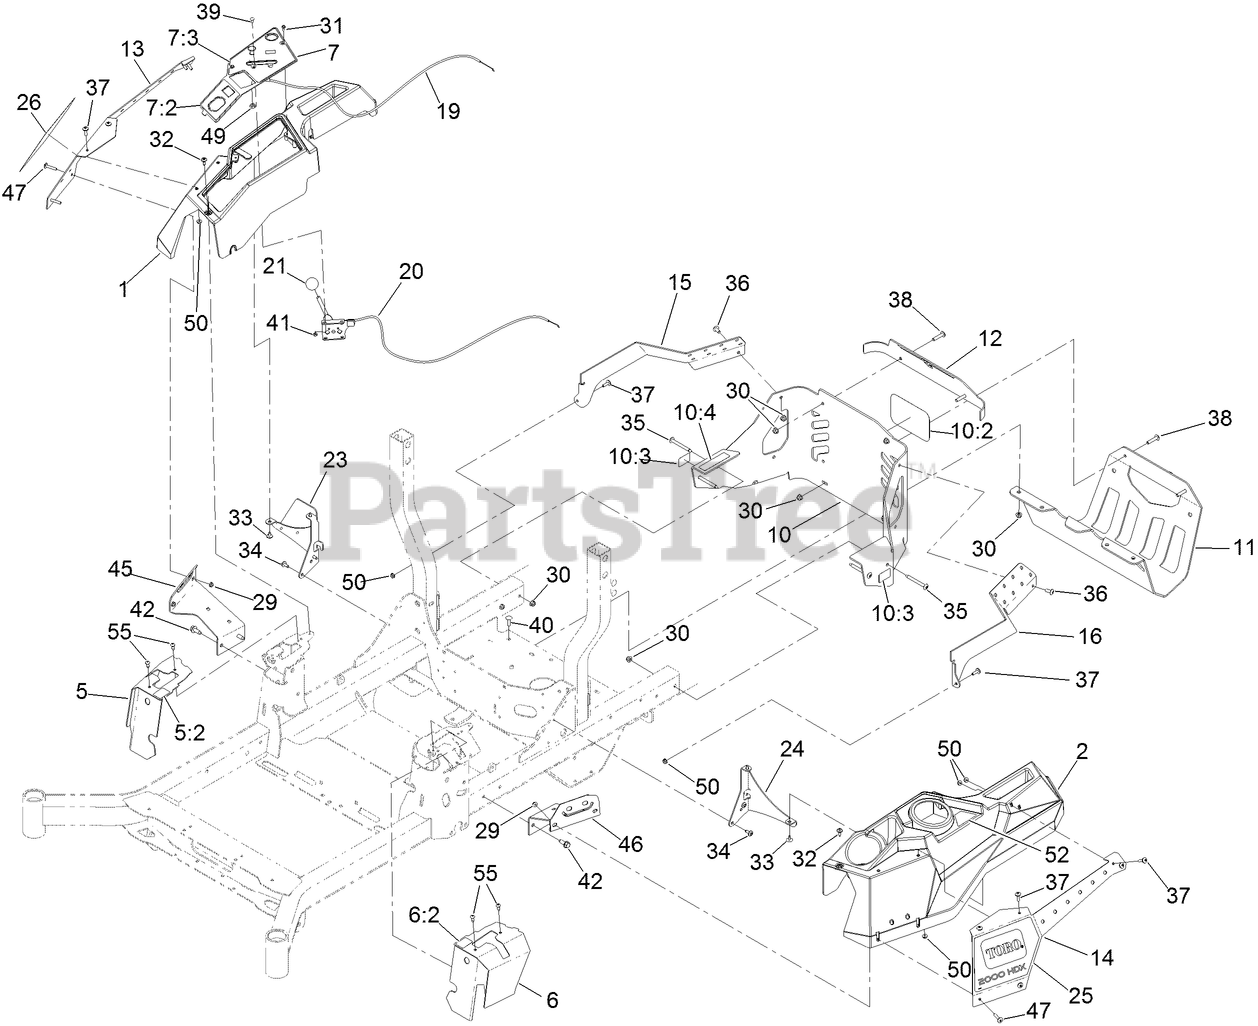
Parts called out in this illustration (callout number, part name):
1	CONSOLE-RH
2	CONSOLE-LH
5	COVER - CONTROL, MOTION
5:2	DECAL-MOTION CONTROL
6	COVER - CONTROL, MOTION
6:2	DECAL-MOTION CONTROL
7	CTRL PANEL ASM
7:2	DECAL-PANEL, CONTROL
7:3	DECAL-PANEL CTRL
10	REAR GUARD ASM
10:2	DECAL
10:3	DECAL-WARNING
10:4	DECAL-ARRESTOR, SPARK
11	GUARD-MUFFLER [BLACK]
12	TRIM-UPPER REAR
13	COVER,POD RH
14	COVER [BLACK]
15	BRACKET-GUARD, RH
16	BRACKET-GUARD, LH
19	CABLE-CONTROL, CHOKE
20	CABLE-CONTROL, THROTTLE
21	KNOB-BALL
23	SUPPORT-CONSOLE, RH
24	BRACKET-CONSOLE, LH
25	DECAL - HDX
26	DECAL - HDX
29	NUT-HF
30	NUT-HF, NI
31	SCREW-HWH
32	SCREW-SHOULDER
33	SCREW-TORX
34	SCREW-TORX
35	SCREW-TORX
36	SCREW-TORX
37	SCREW-TRUSS
38	SCREW-TORX
39	BOLT-CARR
40	SCREW-CARR
41	NUT-LOCK, NI
42	SCREW-FORMING, THREAD
45	BRACKET-SUPPORT, POD (RH)
46	BRACKET-SUPPORT, POD (LH)
47	SCREW-TRUSS
49	NUT-HJ
50	NUT-KEPS
52	DECAL-FILL, FUEL
55	SCREW-TPH THD FORM
